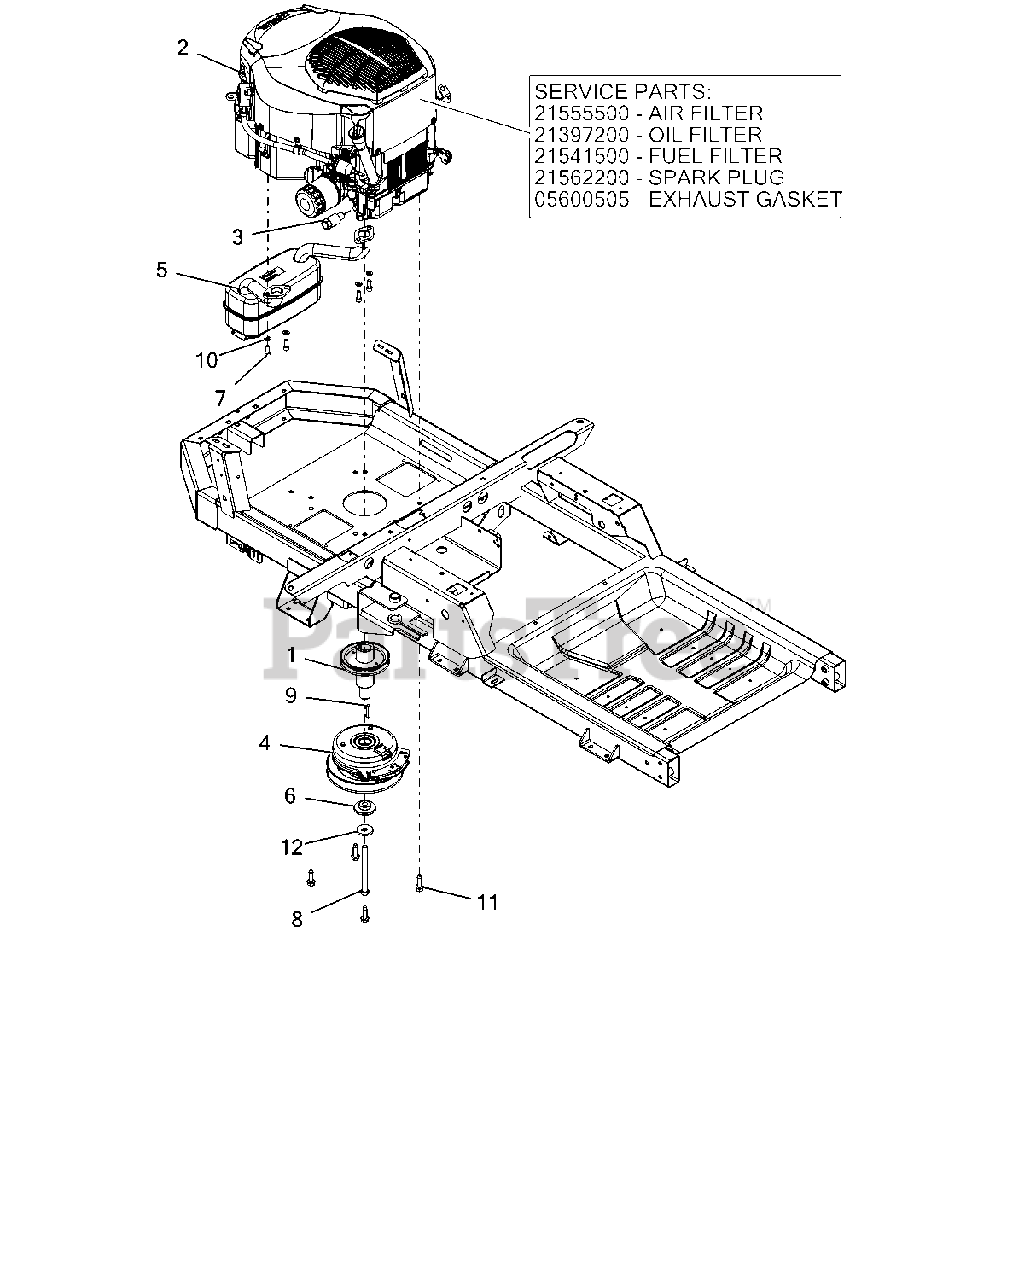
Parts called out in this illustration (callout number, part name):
1	WLDMT, DRIVE SHEAVE (LG XL)CZC
2	FILTER, OIL - KOH CV20
2	FILTER, FUEL
2	GASKET, MUFFLER COURAGE TWIN
2	AIR CLEANER, KOHLER
2	PLUG, SPARK (RFI)
2	ENGINE, KOHLER TWIN - 25HP
3	DRAIN, OIL
4	CLUTCH,105FTLB MONOPOLE 6.83"
5	MUFFLER, KOHLER TWIN
6	BSHG-FLG .469X1.06X.574X2.0
7	SCR-CAP .31-18X.75 S/HD
8	BLT-HEX.438-20X5 GR8 YZ NYTORQ
9	KEY-SQ .25 X 1.25 X .25 SAE
10	@WSHR-LK .31X.078 REG YWZC
11	@SCR-TAP .38-16X1.25 HWH TR YZ
12	WASHER, 7/16" SPRING DISK
